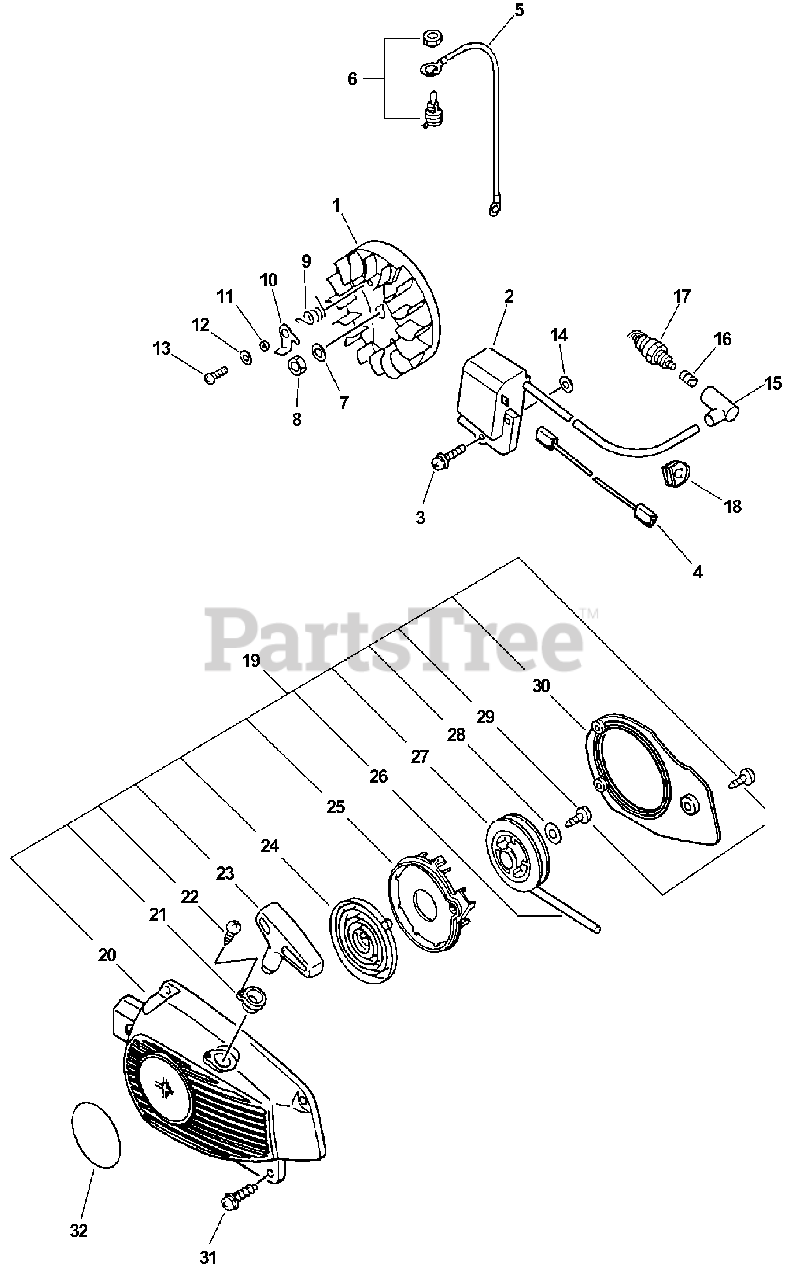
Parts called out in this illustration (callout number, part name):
1	FLYWHEEL
2	COIL, IGNITION
3	SCREW - 5X20
3	SCREW - 5X22
4	LEAD - IGNITION
5	LEAD - GROUND
6	IGNITION SWITCH KIT
7	WASHER - 8
9	SPRING, RETURN
10	PAWL, STARTER
12	WASHER - 5
13	SCREW - 5X12
15	CAP, SPARK PLUG
16	TERMINAL, SPARK PLUG CAP
17	SPARK PLUG -- BPM-7A
17	SPARK PLUG -- BPMR-7A
19	STARTER ASSY
20	CASE, STARTER
21	GUIDE, ROPE
22	SCREW - 3X14
23	GRIP, STARTER
24	REWIND SPRING ASSY
25	PLATE, STARTER
26	ROPE, STARTER - 3X850
27	REEL, ROPE
29	SCREW - 4X14
31	SCREW - 4X16
32	LABEL - ECHO
